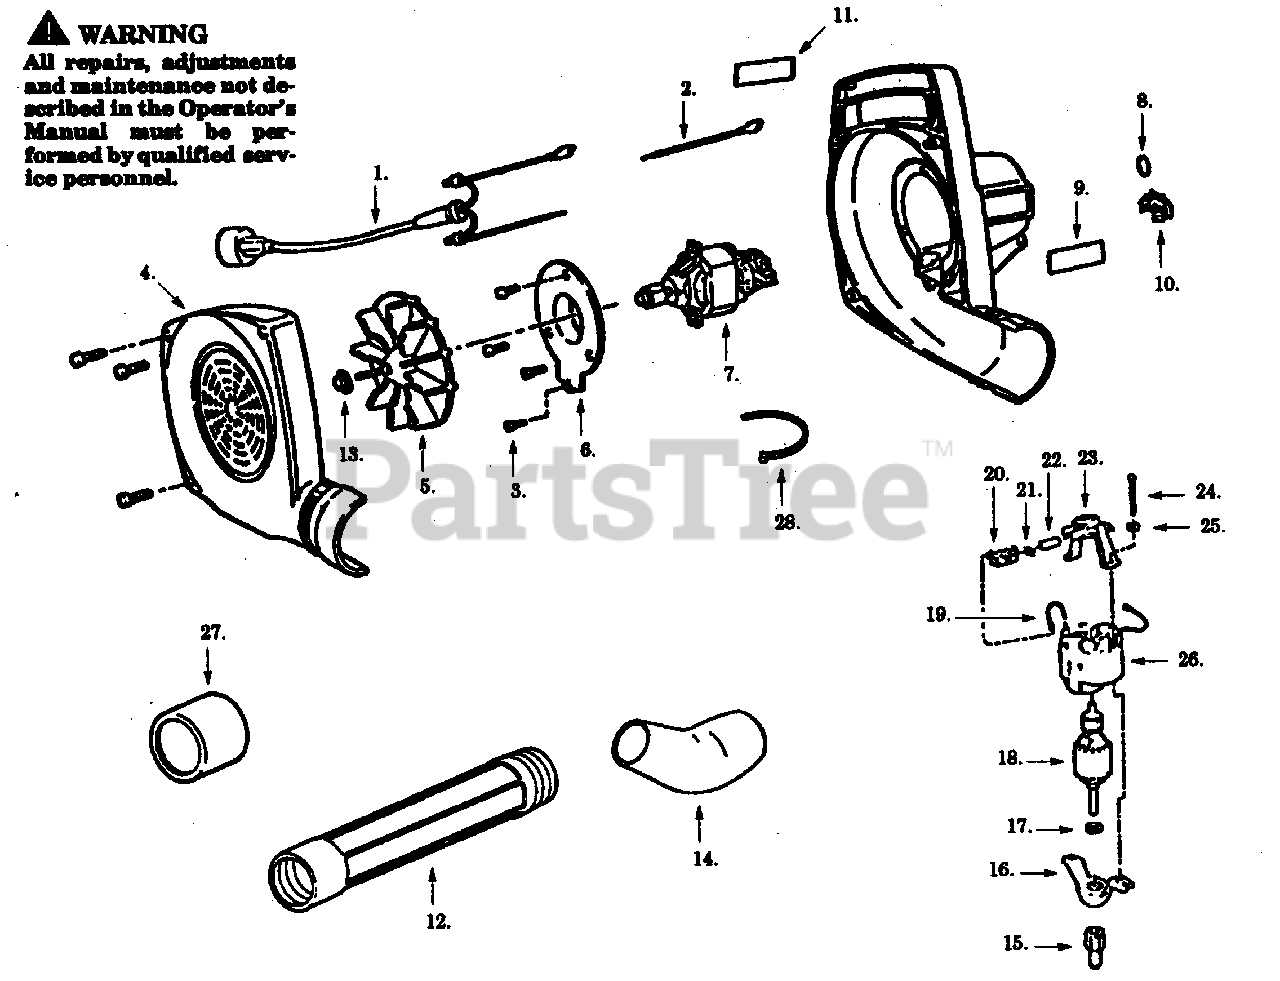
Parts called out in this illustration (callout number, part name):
1	Harness Ass'y.
2	Leadwire Ass'y.
4	Housing Set
5	Impeller
6	Mounting Plate
7	Motor/Adapter Ass'y.
8	U.L. Label (Not a serviceable part)
9	Motor Hsg. Label
10	Switch Ass'y.
11	Warning Label
12	Outlet Tube
13	Push Nut
14	Curved Nozzle
15	Impeller Adapter
16	Endbell Ass'y. (Drive)
17	Thrust Washer
18	Armature Ass'y.
19	Wire/Terminal Ass'y.
20	Brush Holder
21	Brush Spring
23	Endbell Ass'y. (Brush)
25	Lockwasher
26	Field Ass'y.
28	Tie Strap
